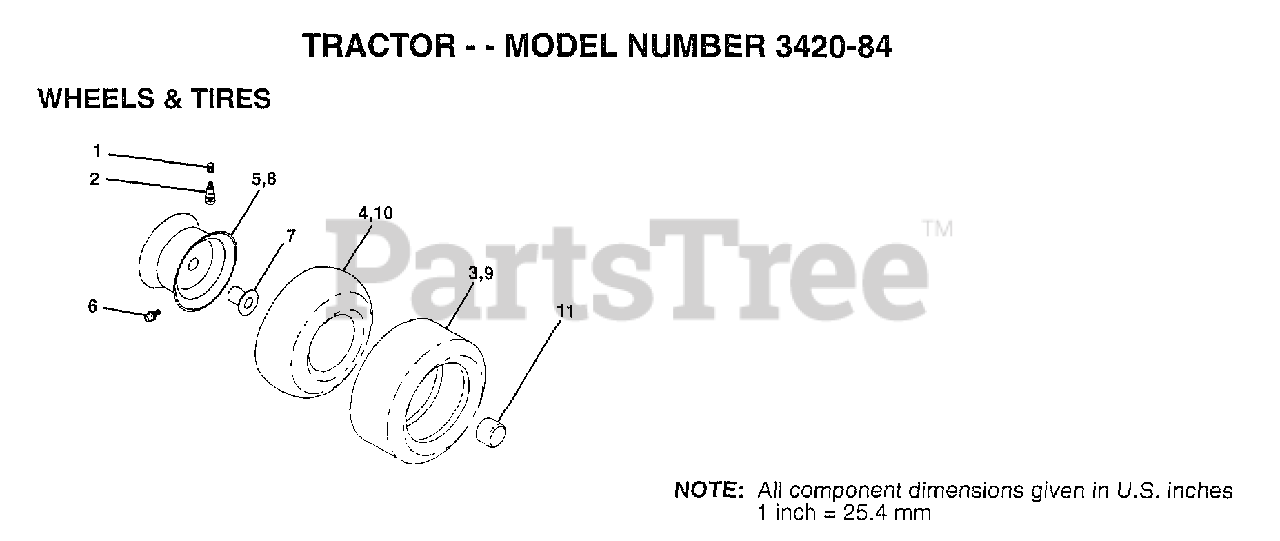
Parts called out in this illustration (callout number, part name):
1	VALVE CAP
2	VALVE STEM LT
4	TUBE.5.3/4.5/6
5	"RIM,FRT T"
6	FITTING LT
7	"FLANGE, BEARING"
8	"RIM 8"""
9	TIRE.20X8-8
10	TUBE.18X9.5-8
11	HUB CAP
